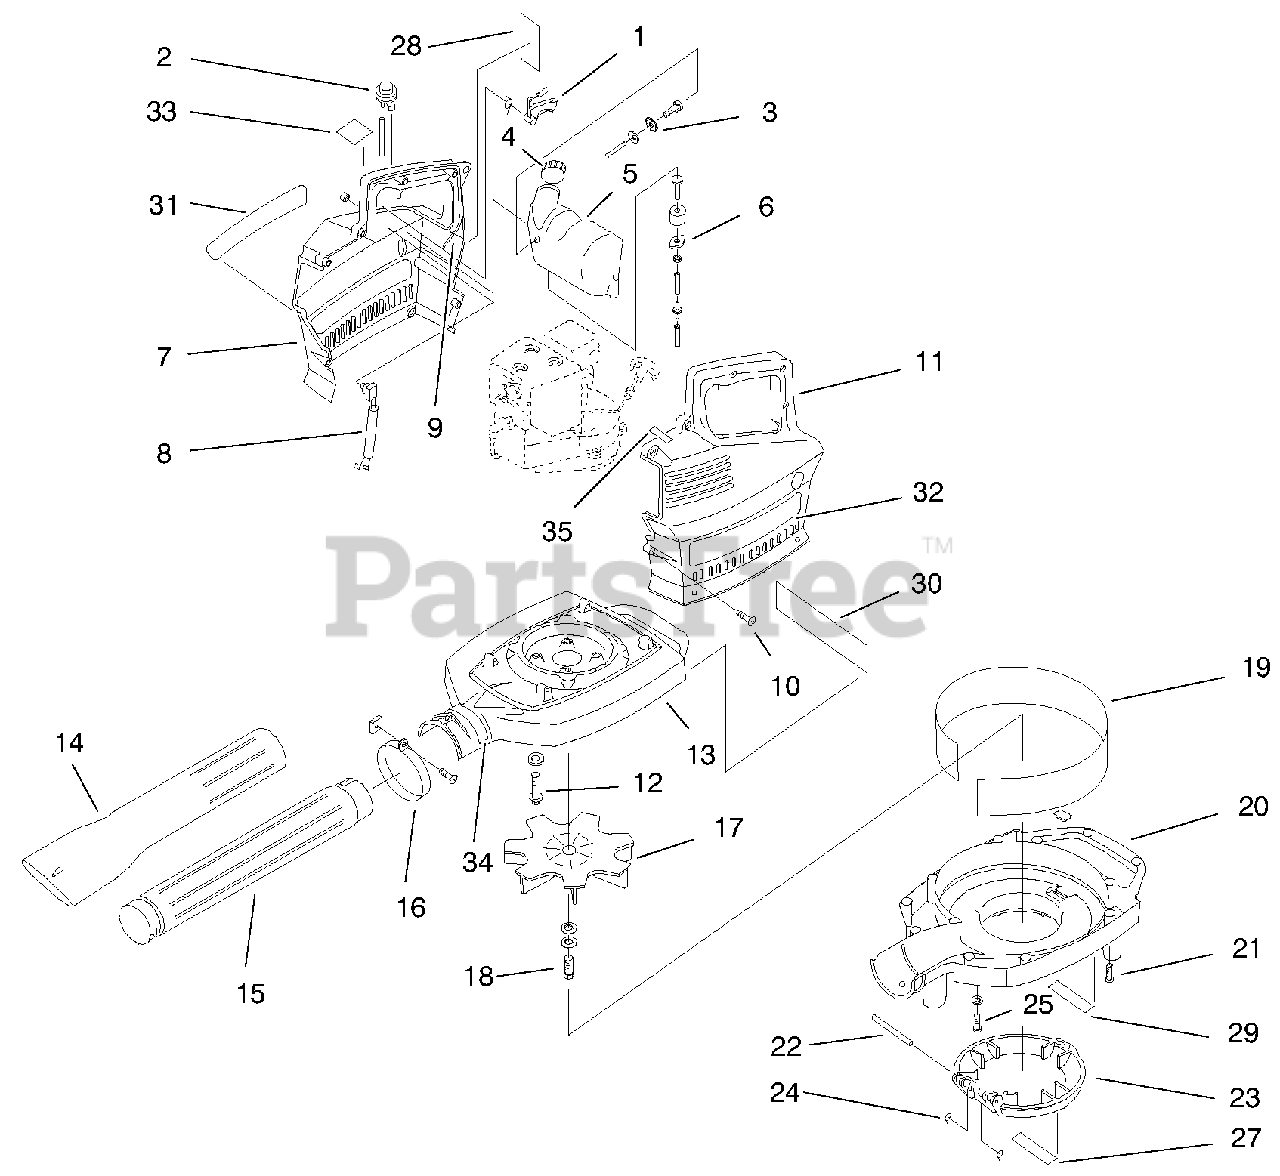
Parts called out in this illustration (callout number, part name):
1	Trigger Asm.
2	Primer Bulb and Hose Asm.
3	Return Line Asm.
4	Fuel Cap Asm.
5	Complete Fuel Tank Asm. (Incl. Ref. #3, 4 and 6)
6	Fuel Line Asm.
7	R.H. Engine Cover
8	Switch and Lead Asm.
9	Throttle Wire & Housing Asm.
10	Mounting Screw
11	L.H. Engine Cover
12	Mounting Screw Asm.
13	Upper Blower Housing
14	Blower Tube W/Nozzle
15	Blower Tube
16	Clamp Asm.
17	Impeller
18	Mounting Bolt Asm.
19	Impact Shield
20	Lower Blower Housing
21	Mounting Screw
22	Hinge Shaft
23	Intake Cover
24	Spring Set
25	Mounting Screw Asm.
27	Decal-Warning
28	Decal-69 DBA ANSI
29	Decal-Push Tab
30	Decal-Fuel & Oil Mix
31	Decal-Toro R.H.
32	Decal-Toro L.H.
33	Decal-Prime
34	Decal-Safety Symbol
35	Decal-Warning
